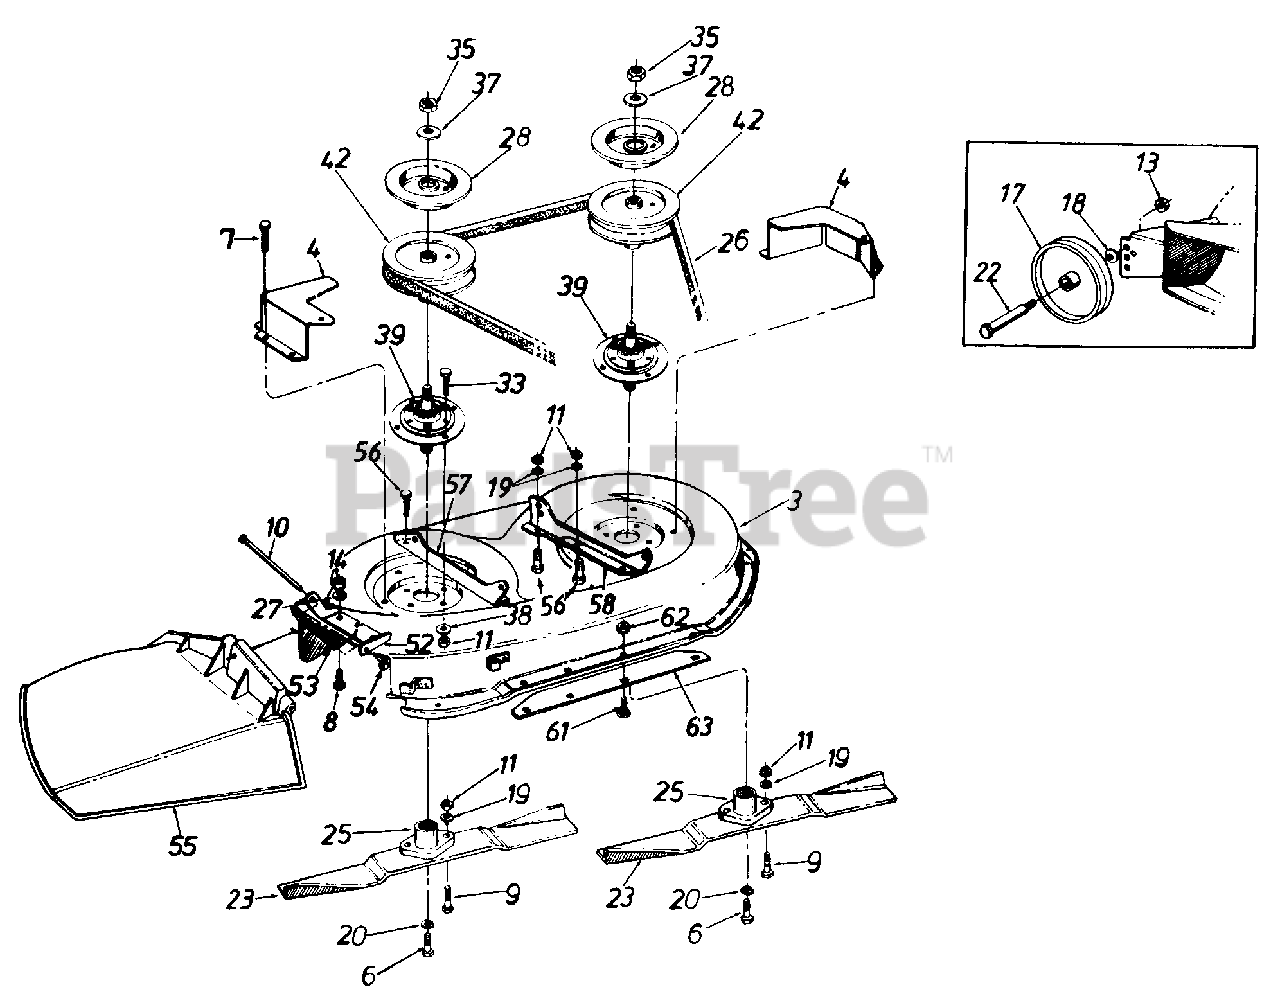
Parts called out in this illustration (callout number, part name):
3	36" Deck Ass'y.
7	Hex Bolt 1/4-28 x .62" Lg.
8	Truss Mach. Scr. 1/4-20 x .75"
9	Hex Bolt Special 5/16-24 x 1.0"
10	Hinge Pin
11	Hex Nut 5/16-24 Thd.
13	Hex Top L-Nut 3/8-16 Thd.
14	Hex Nut 1/4-20 Thd.
17	Deck Wheel-5"
18	Bell-Wash. .40" I.D. x .88" O.D.
19	L-Wash. 5/16" I.D.
20	L-Wash. 3/8" I.D.-H.D.
22	Shld. Bolt .498" Dia. x 1.53"
23	High-Lift Blade
25	Blade Adapter
26	"V"-Belt
27	Bell-Wash. 1/4" I.D.
28	Brake Disc
33	Rib Neck Bolt 5/16-24 x .84" Lg.
35	Hex Jam Nut 5/8-18 Thd.
37	L-Wash. 5/8" I.D.*
38	L-Wash. 5/16" I.D.*
39	Blade Spindle Ass'y. Comp.- Incl. Ref. 33
42	5" Dia. Pulley
52	Hinge Mtg. Brkt.
53	Torsion Spring
54	Push Nut
55	Chute Ass'y. Comp.
56	Hex Bolt 5/16-24 x .75" Lg.
61	Carr. Bolt 1/4-20 x .5" Lg.
62	Hex Sems Nut 1/4-20 Thd.
